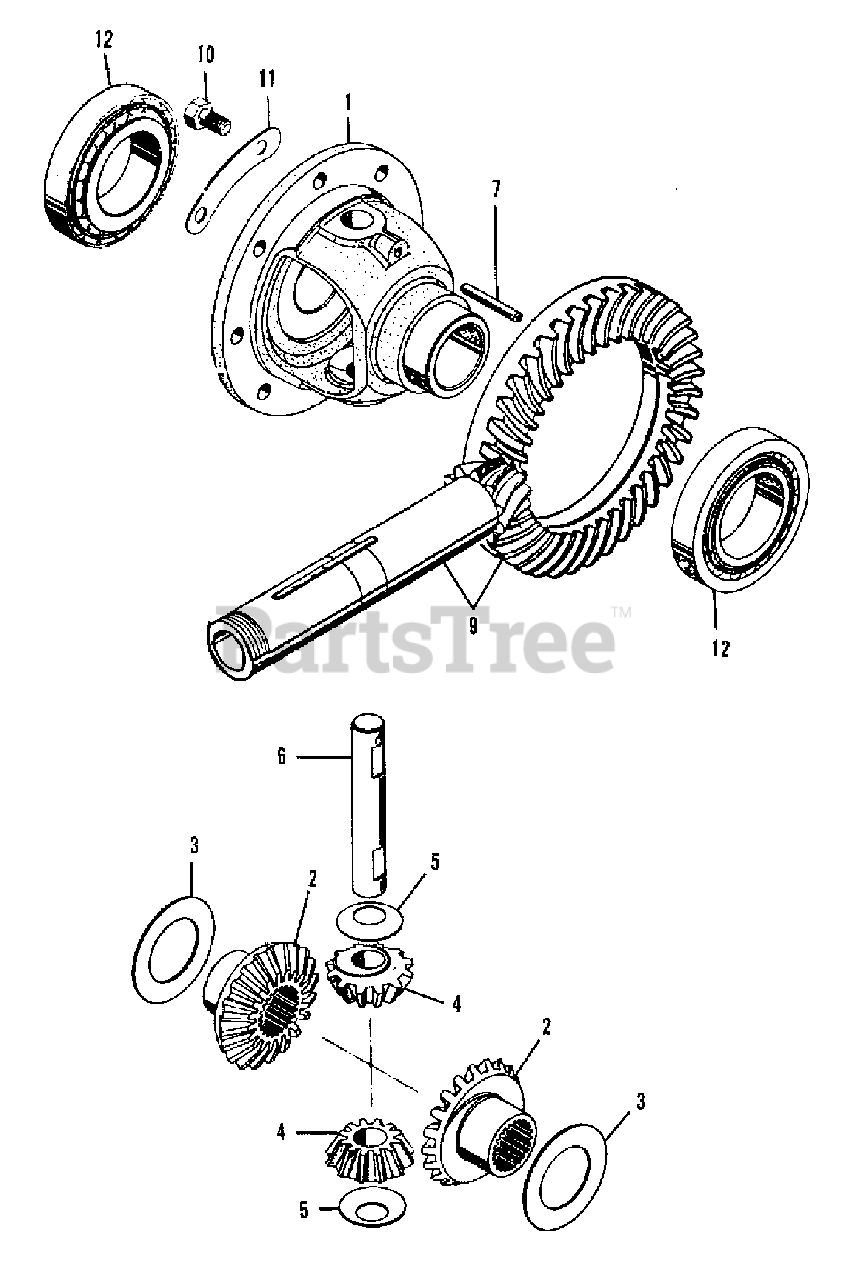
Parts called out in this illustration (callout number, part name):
2	GEAR, side
3	WASHER, thrust
4	GEAR, pinion
5	WASHER, pinion
6	SHAFT, pinion
7	PIN, M6 x 50 lock
8	DIFFERENTIAL SUB ASSEMBLY (Incl. Items 1 thru 7)
9	GEAR KIT, (Ring gear & drive pinion shaft)
10	SCREW, lock - ring gear
11	WASHER, lock
12	BEARING, tapered roller
